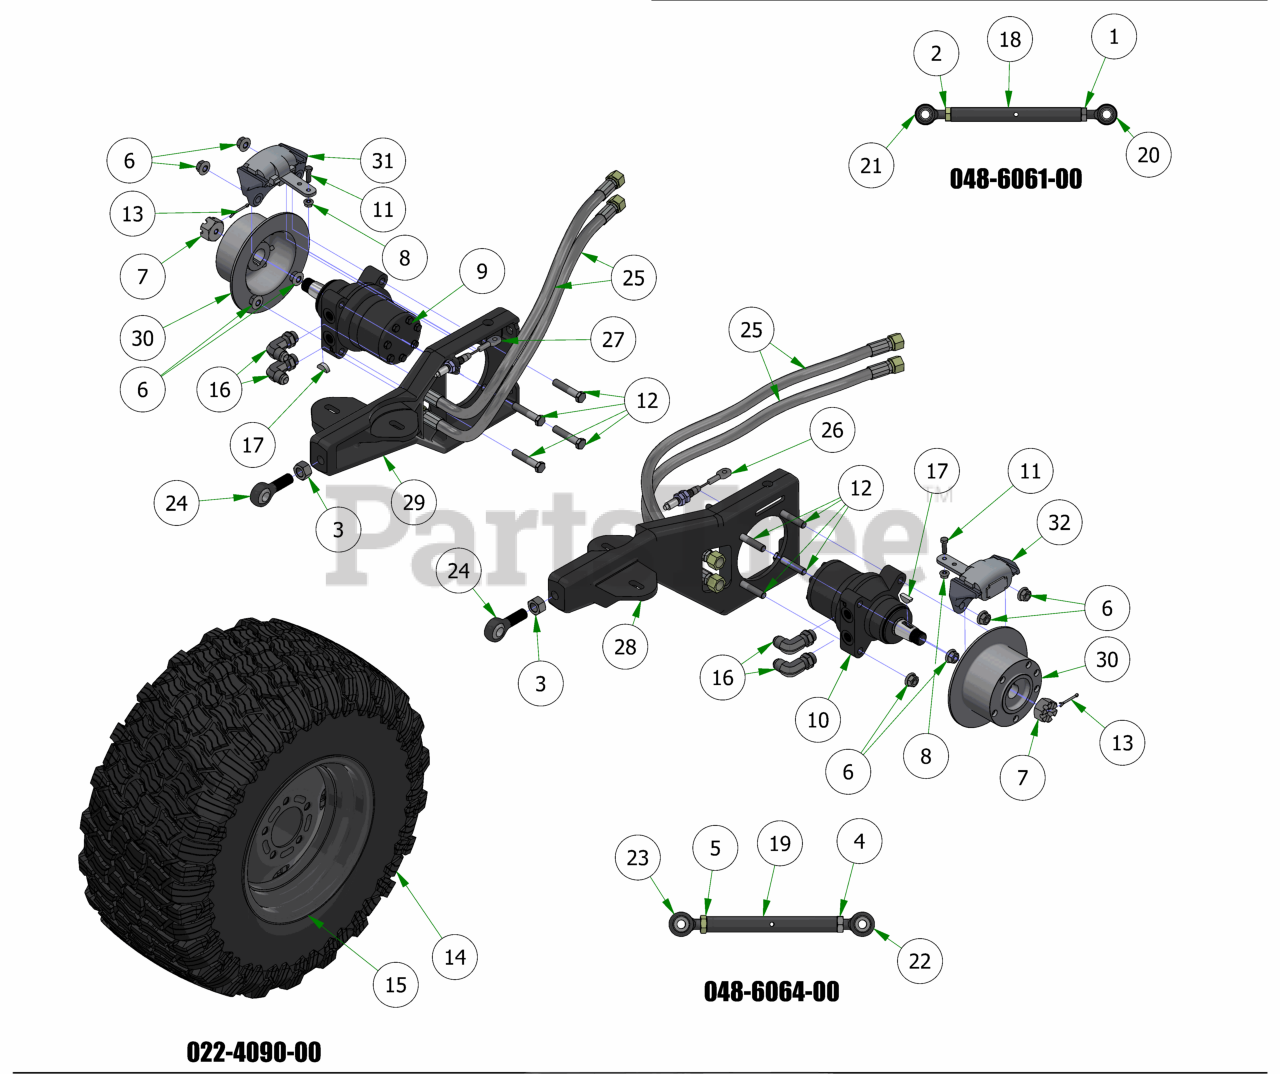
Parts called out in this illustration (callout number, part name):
1	5/8-11 HEX JAM NUT ZINC
2	NUT, 5/8-18LH
3	3/4"-16 Fine Full Nut
4	3/4-16 HEX JAM NUT ZINC
5	3/4-16 LH HEX JAM NUT ZINC
6	1/2-13 Gr 8 Centerlock Flange Nut
7	1" Castle Nut for HydroGear Wheel Motor
8	5/16-18 NYLON INSERT FLANGE LOCKNUT ZINC
9	18cc Parker Wheel Motor- Right
10	18cc Parker Wheel Motor- Left
11	5/16-18 X 1 HEX CAP SCREW (GR.5) ZINC
12	1/2-13 x 2.75 Gr. 8 Hex Head Bolt
13	1/8 X 1-1/2 COTTER PIN ZINC
14	2019 26x12-12 Reaper Turf Tire
15	2019 10.5" Wheel
16	2019 Rouge/Renegade Wheel Motor 90* Fitting #6801-10L
17	Woodruff Key
18	2019 Suspension Link Body
19	Rear Radius Rod, 3/4 Body
20	2019 RH 5/8" Heim
21	2019 LH 5/8" Heim
22	3/4-16 x 5/8 RH Heim
23	3/4-16 x 5/8 LH Heim
24	3/4-16 RH Male Rod End
25	2019 Renegade Hydro Hose
26	2019 Short Brake Cable-Suspension Models
27	2019 Long Brake Cable-Renegade, Rogue
28	2019 Left Trailing Arm
29	2019 Right Trailing Arm
30	Brake Disk
31	XP/AOS Right Brake Caliper
32	XP/AOS Left Brake Caliper
